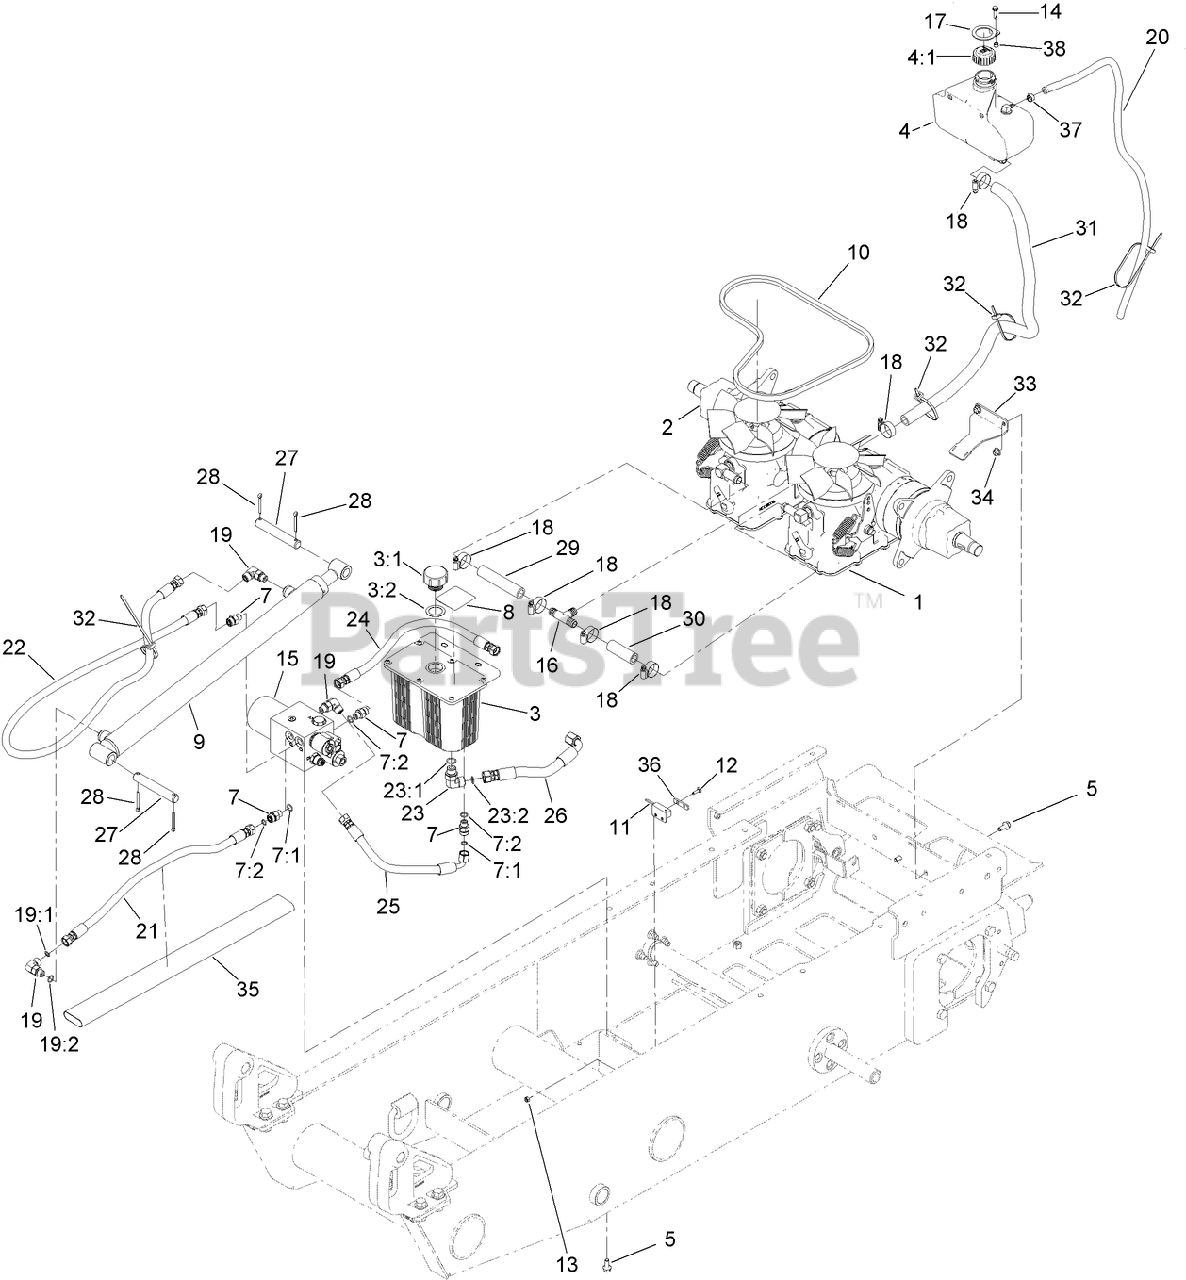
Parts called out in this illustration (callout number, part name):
1	LH HYDRO TRANSAXLE ASM
2	RH HYDRO TRANSAXLE ASM
3:1	CAP-RESERVOIR, HYD
3:2	GASKET-CAP
4	TANK-HYDRAULIC
4:1	CAP-VENTED
5	SCREW-HHF
7	FITTING-STRAIGHT
7:1	O-RING
7:2	O-RING
8	DECAL-WARNING
9	CYLINDER-HYDRAULIC
10	BELT AND SPRING KIT
11	SWITCH-PROXIMITY
12	SCREW-CARR
13	NUT-LOCK, NI
15	HYDRAULIC MANIFOLD ASM
17	LOCK-TANK
18	CLAMP-SC BAND
19	FITTING-ELBOW, 90 DEG
19:1	O-RING
19:2	O-RING
20	HOSE-BREATHER, TRANSMISSION
21	HOSE-HYDRAULIC
22	HOSE ASM-HYD
23	FITTING-ELBOW, 90 DEG
23:1	O-RING
23:2	O-RING
24	HOSE ASM-HYD
25	HOSE ASM-HYD
26	HOSE ASM-HYD
27	PIN-PIVOT
28	PIN-COTTER
29	HOSE-HYD, HYDRO
30	HOSE-HYD, HYDRO
31	HOSE-HYD, HYDRO
32	TIE-CABLE
33	BRACKET-HOSE RETAINER
34	NUT-HF, NI
35	SLEEVE-PROTECTIVE
36	PLATE-SWITCH, PROXIMITY
37	CLAMP-HOSE
38	SPACER
